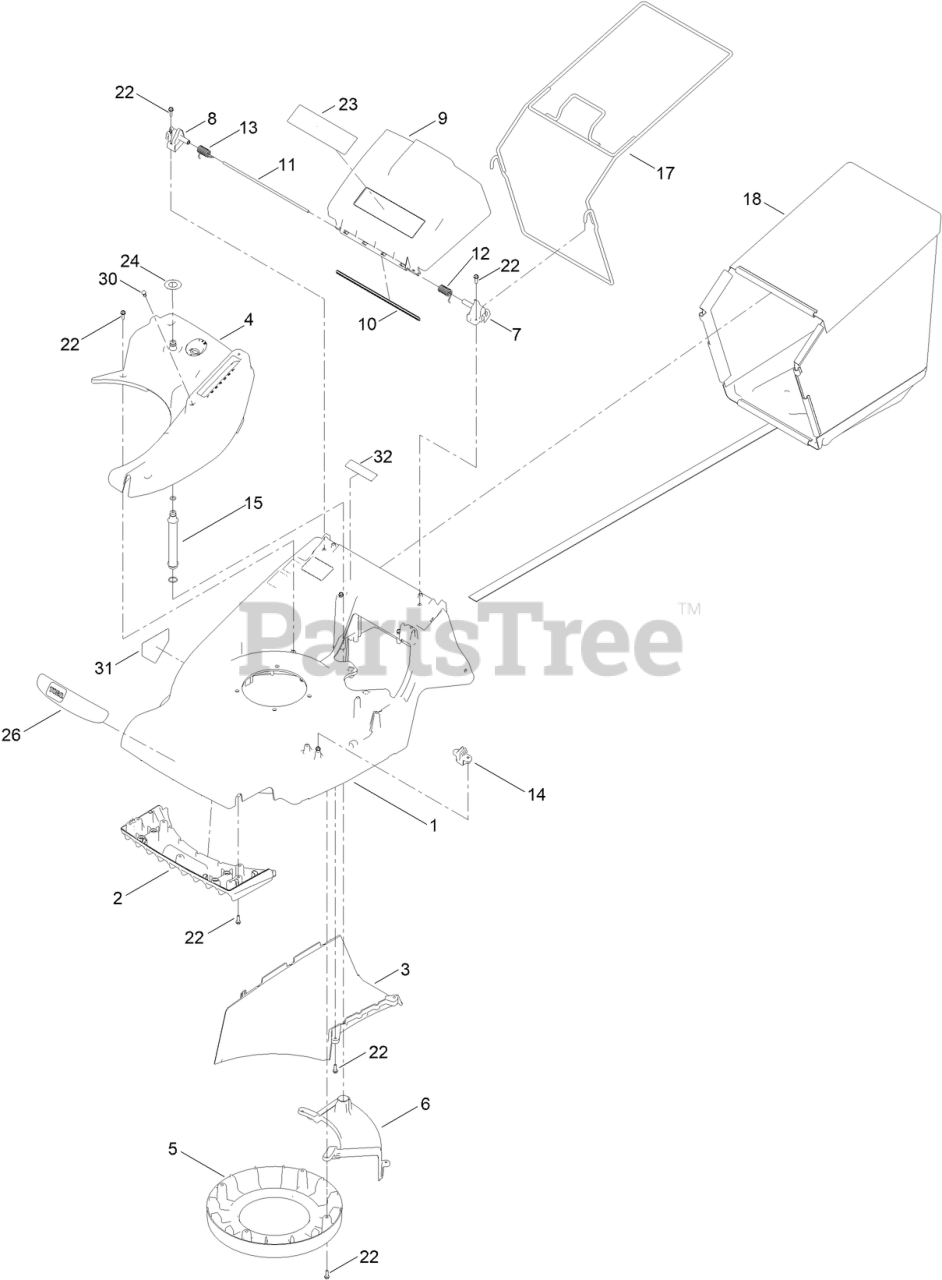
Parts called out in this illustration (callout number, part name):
1	HARRIER DECK ASSEMBLY
2	FINS-FRONT
3	PLATE-THROW
4	TRIM-TOP
5	COVER-BELT
6	COVER-BELT
7	MOUNT-DEFLECTOR, LEFT
8	DEFLECTOR MOUNT RIGHT
9	DEFLECTOR-REAR
10	DEFLECTOR-SEAL, REAR
11	ROD-DEFLECTOR
12	SPRING-DEFLECTOR, LEFT
13	SPRING-DEFLECTOR, RIGHT
14	ROD-SUPPORT
15	WASHPORT ADAPTER ASSEMBLY
17	GRASSBAG-FRAME
18	GRASSBAG-FABRIC, TORO
22	SCREW-TAPTITE
23	DECAL-SAFETY
24	DECAL-QUICK WASH
26	DECAL-PROSTRIPE 560
30	RIVET-PUSH, PLASTIC
31	DECAL-DANGER
32	DECAL-ARRESTOR, SPARK
